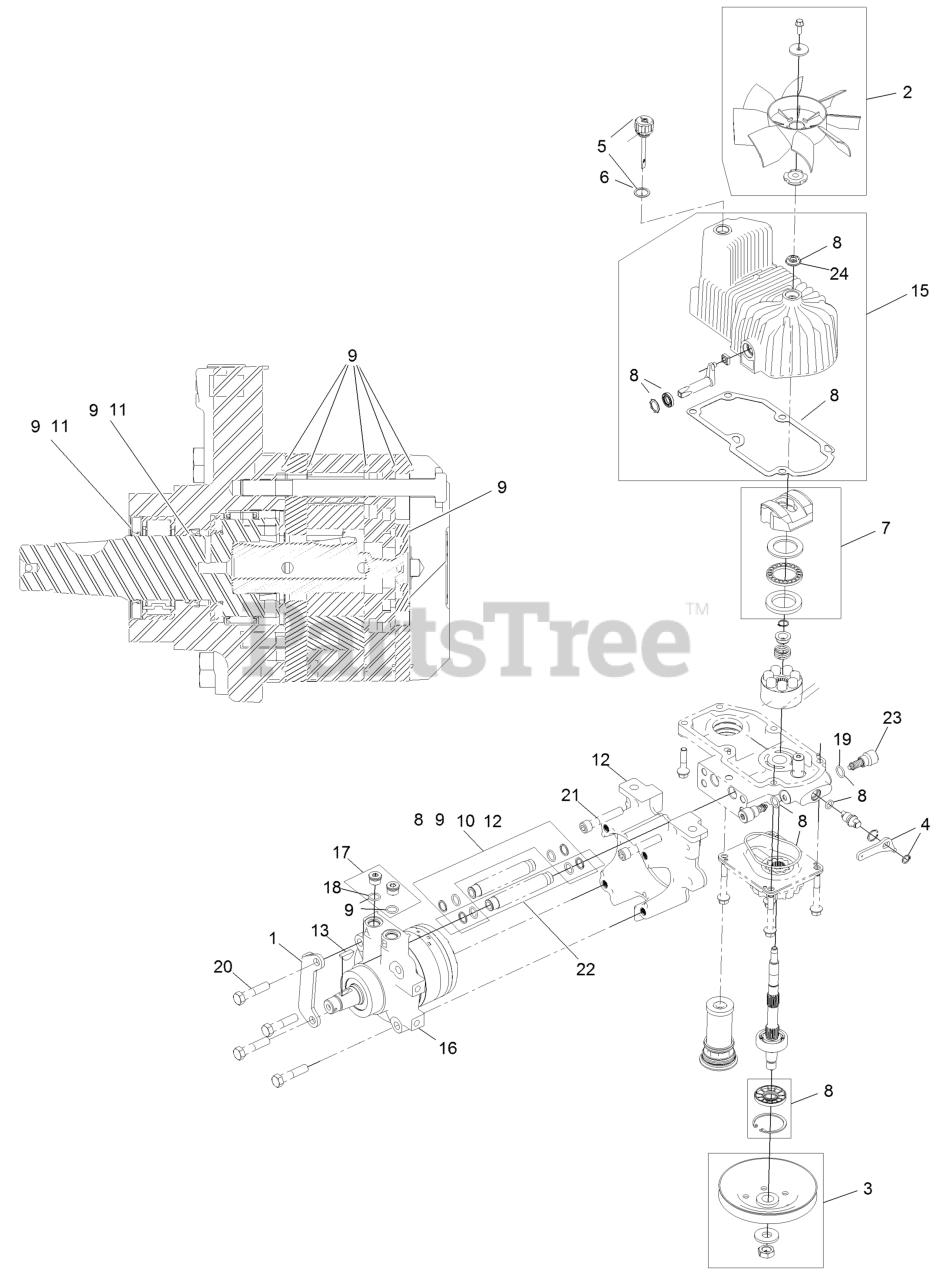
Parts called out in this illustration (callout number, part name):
1	MOUNT-SHOE, HORSE
2	FAN KIT
3	PULLEY KIT
4	HANDLE-BYPASS VALVE, HYDRO
5	DIPSTICK-HYDRO W/GASKET
6	GASKET-DIPSTICK, HYDRO
7	SWASH BLOCK KIT
8	PUMP SEAL KIT
9	MOTOR SEAL KIT
10	TUBE SEAL KIT
11	OUTPUT SHAFT SEAL KIT
12	NOSE CUP-UHT
13	KEY-WOODRUFF
15	HOUSING-HYDRO, RH
16	MOTOR-HYDRAULIC RH 240CC
17	MAGNETIC PLUGS SERVICE KIT
19	O-RING-CHECK VALVE
20	SCREW HH
21	SCREW-HSH
22	HYDRAULIC TUBE KIT
23	SHOCK VALVE, 12CC HYDRO
24	SEAL-FAN DRIVE
